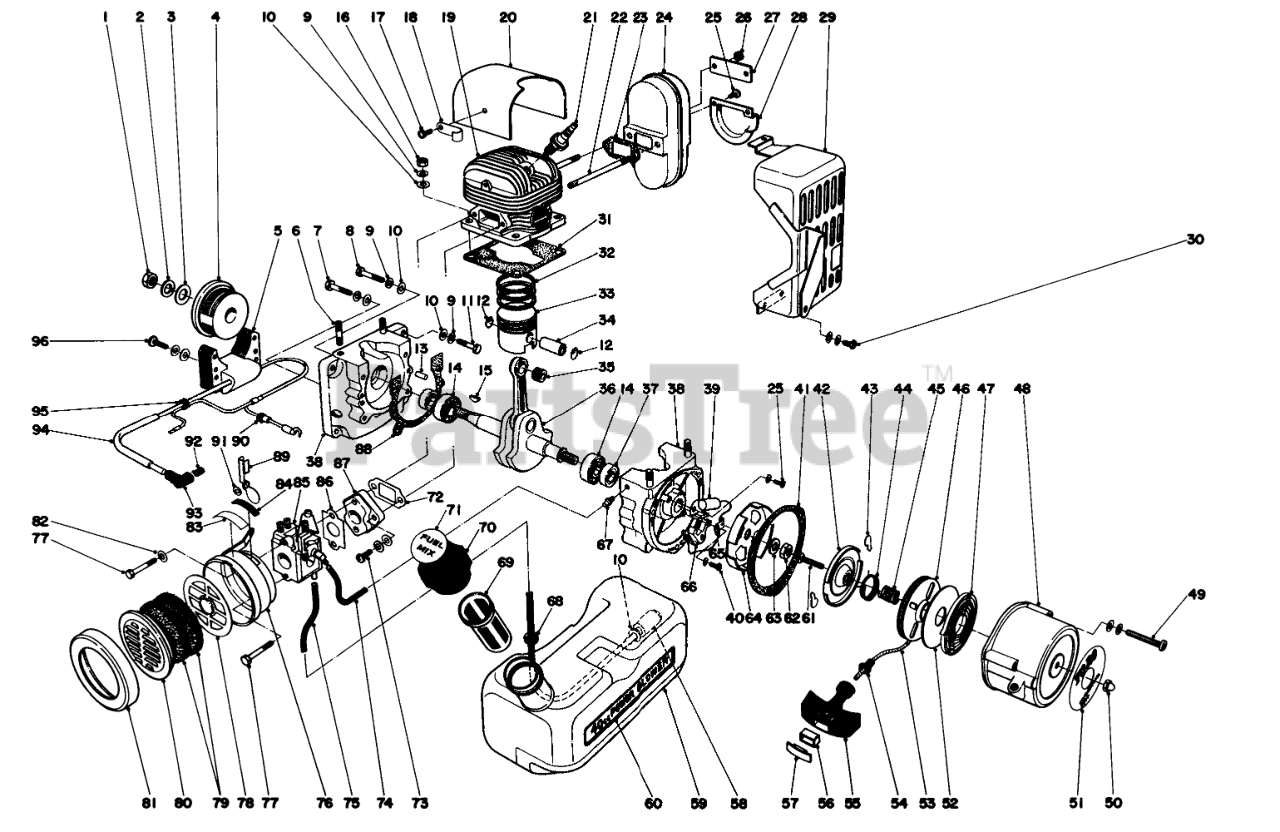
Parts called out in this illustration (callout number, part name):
2	Spring Washer
3	Washer
4	Rotor
5	Ignition Coil
6	Stud Bolt
9	Washer
10	Washer
12	CIRCLIP PISTON PIN
13	Knockpin
14	Ball Bearing
15	Woodruff Key
18	Clamp
19	Cylinder
20	Cylinder Cover
21	Spark Plug
22	STUD BOLT
23	Gasket Muffler
24	Muffler
25	SCREW
26	Locknut
27	Washer
28	Muffler Lid
29	Muffler Cover
30	Screw
31	Packing Cylinder Base
32	PISTON RING
33	Piston
34	Piston Pin
35	Needle Bearing
36	Crankshaft Assembly
37	Oil Seal
38	Crankcase Set (Incl. Ref. #13 & 67)
39	CONDENSER
41	STARTER CASE GASKET
42	FRICTION PLT
43	RATCHET
44	RATCHET SPRING
45	SPRING
46	Recoil Drum
47	REWIND SPRING
48	Starter Case
49	SCREW
50	Cap Nut
51	Decal-Commercial Duty
52	Side Plate, Starter
53	Starter Rope
54	Rope Guide
55	Starter Handle
56	End Piece
57	Cap, Starter Handle
58	Fuel Strainer
59	Fuel Tank
60	Decal-40cc
61	Screw
63	Washer
64	PAWL CATCHER
65	Clamp
66	CONTACT BRK POINT SET
67	Connector
68	GROMMET
69	Fuel Strainer
70	Fuel Cap Assembly
71	Decal-Fuel Mix
72	Gasket
73	SCREW
75	FUEL PIPE
76	Case, Air Cleaner (Incl . Ref . #84)
79	Air Filter
80	AIR CLEANER COVER
81	AIR CLEAN COVER HLDR
82	Washer
83	Decal-Caution
84	Grommet
85	CARBURATOR ASM
86	GASKET
87	INSULATOR
88	Packing, Crankcase
89	Choke Shutter
90	Grommet
91	Spacer
92	Coil Spring-Plug Cap
93	Cap-Spark Plug
94	Sleeve
95	Grommet
